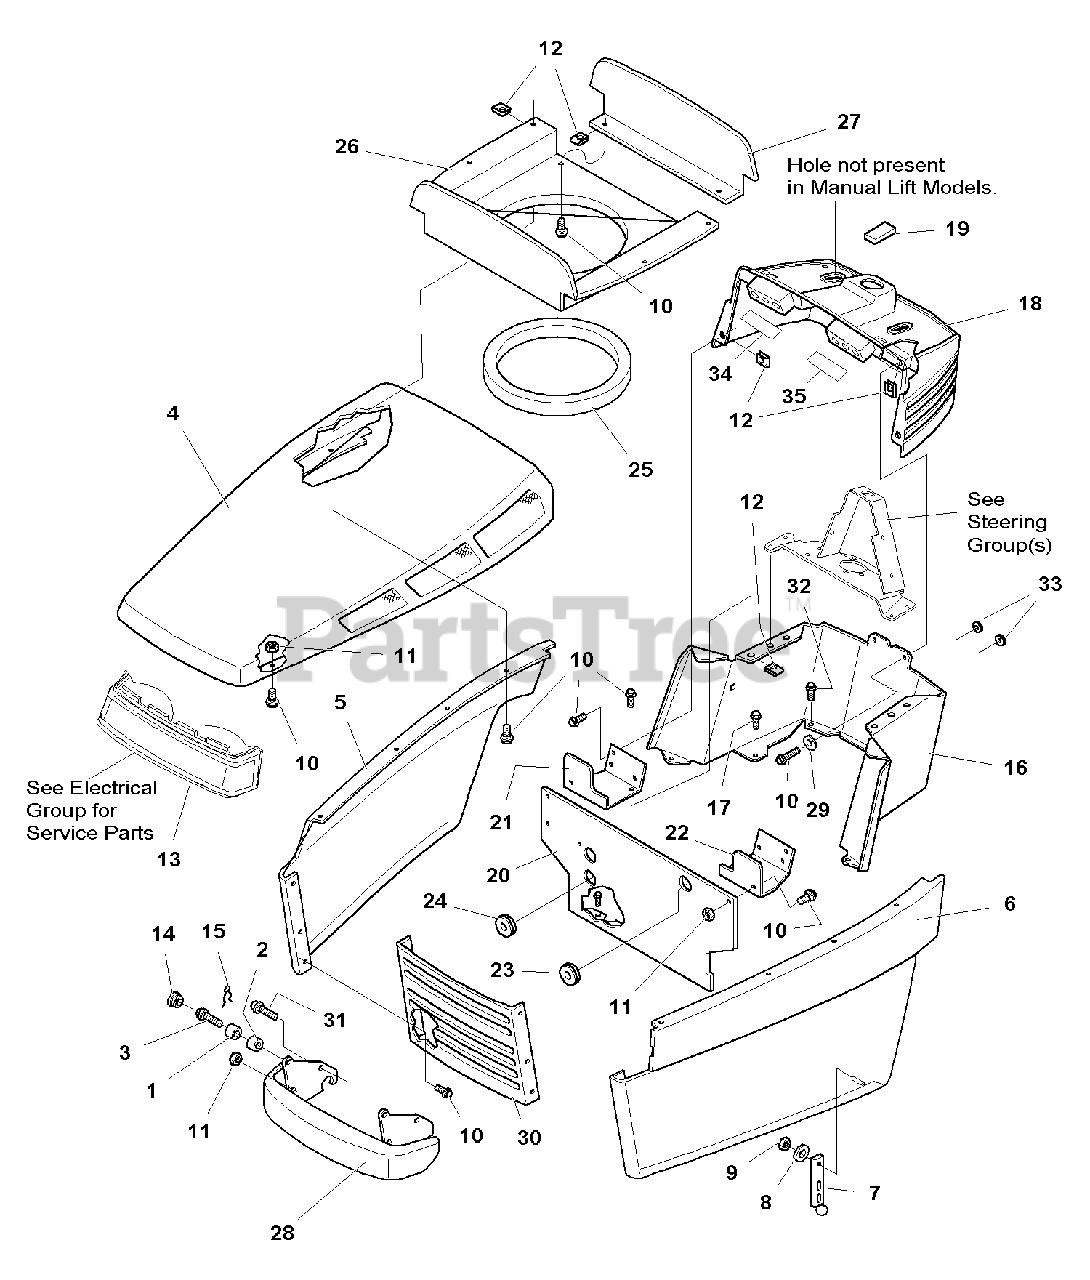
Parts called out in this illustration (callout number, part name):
2	PIVOT, Hood
3	CAPSCREW, Hex Head, Taptite, 5/16-18 X 1
4	HOOD, Orange
5	SIDE PANEL ASSEMBLY, RH, Orange
5	SIDE PANEL ASSEMBLY, RH, Red
6	SIDE PANEL ASSEMBLY, LH, Orange
6	SIDE PANEL ASSEMBLY, LH, Red
7	STRAP, Hood
8	WASHER, 3/16
9	NUT, Hex Nylon Lock, #10-24
10	CAPSCREW, Hex Head, Whiz Lock, 1/4-20 x 5/8
11	NUT, Hex Nylon Lock, 1/4-20
12	PAL NUT, 1/4-20
13	HEADLIGHT ASSEMBLY (See Electrical Group for Service Parts)
14	SPACER, Hood
15	CLIP, Hairpin
16	DASH ASSEMBLY, Lower
17	CAPSCREW, Hex Head, Taptite, 1/4-20 x 1/2
18	DASHBOARD ASSEMBLY (18HP & 20HP Hydraulic Lift Models)
18	DASHBOARD ASSEMBLY (18HP Maunal Lift Models)
20	BULKHEAD
21	SUPPORT, Bulkhead, RH
22	SUPPORT, Bulkhead, LH
23	GROMMET, Bulkhead
24	GROMMET, Wire Harness
28	BUMPER ASSEMBLY
29	WASHER, 1/4
30	GRILLE
31	CAPSCREW, Hex Head, Taptite, 5/16-18 x 5/8
32	CAPSCREW, Hex Head, Taptite, 1/4-20 x 3/8
34	DECAL, R. H. Indicator
35	DECAL, L. H. Indicator
